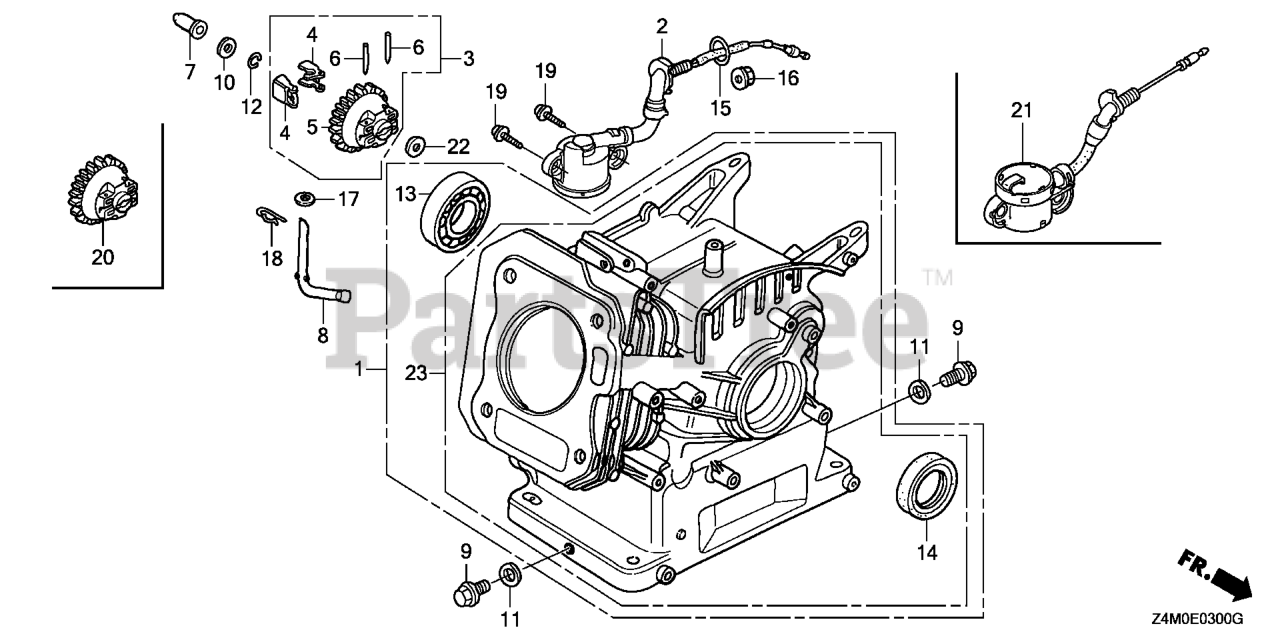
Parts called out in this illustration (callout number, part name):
1	CYLINDER ASSY. (OIL ALERT)
3	GOVERNOR ASSY.
4	WEIGHT, GOVERNOR
5	HOLDER, GOVERNOR WEIGHT
6	PIN, GOVERNOR WEIGHT
7	SLIDER, GOVERNOR
8	SHAFT, GOVERNOR ARM
9	BOLT, DRAIN PLUG
11	WASHER, DRAIN PLUG (10.2MM)
12	CLIP, GOVERNOR HOLDER
13	BEARING, RADIAL BALL (6205)
13	BEARING, RADIAL BALL (6205) (NSK)
14	OIL SEAL (25X41X6)
14	OIL SEAL (25X41X6) (ARAI) (NOT AVAILABLE)
15	O-RING (14MM) (ARAI) Use up to Engine SN 2949254.
15	O-RING (14MM) (NOK)
16	NUT, FLANGE (10MM)
17	WASHER, PLAIN (6MM)
18	PIN, LOCK (8MM)
19	BOLT, FLANGE (6X12) Use up to Engine SN 1543277.
21	SWITCH ASSY., OIL LEVEL
22	WASHER, PLAIN (6MM)
